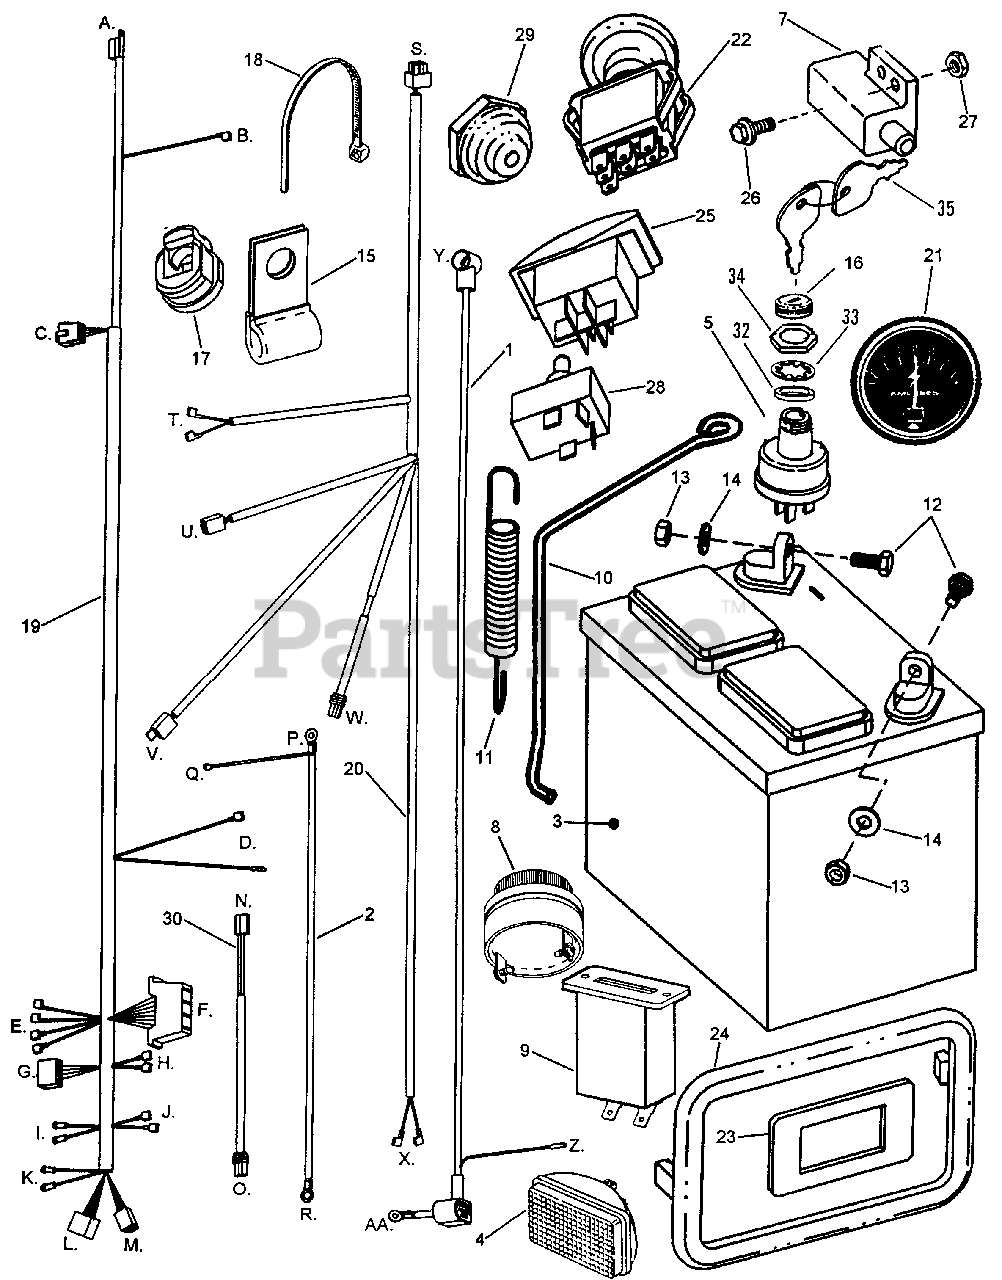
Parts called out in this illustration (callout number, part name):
1	CABLE, Battery-Positive
2	CABLE, Battery-Negative
3	BATTERY, 11 Plate- 375CCA
4	HEAD LIGHT
5	SWITCH, Ignition-Afterfire Solenoid
7	SWITCH, DPDT
8	BUZZER, Pulsing
9	HOUR METER, D.C. Ser. 1500
10	BRACKET, Battery
11	SPRING, Battery
12	SCREW, 1/4-20 x 5/8", Hex Head Cap, Gr. 5
13	NUT, 1/4-20 Hex Center Lock, Grade B or 5
14	WASHER, .28 I.D. x .63 O.D. x .06 Flat
15	CLIP, Harness
16	BEZEL
17	STRAIN RELIEF, Wire
18	CABLE TIE, 7"
19	HARNESS, Control Panel
20	HARNESS, Front
21	ASSEMBLY, Ammeter and Clamp
22	SWITCH, PTO
23	SPACER, PTO Switch
24	BEZEL, Headlight
25	SWITCH, Lights
26	SCREW, #10-32 x 5/8" Hex Wash. Hd. Machine, Gr. 5
27	NUT, #10-32 Hex Nyloc
28	SWITCH, Self Centering, Deck Lift
29	SEAL, Switch
30	HARNESS, Deck Lift
32	SPACER, 5/8"
33	WASHER, 5/8" Internal Tooth Lock
34	NUT, 5/8-32 Hex
35	KEY, and Ring
